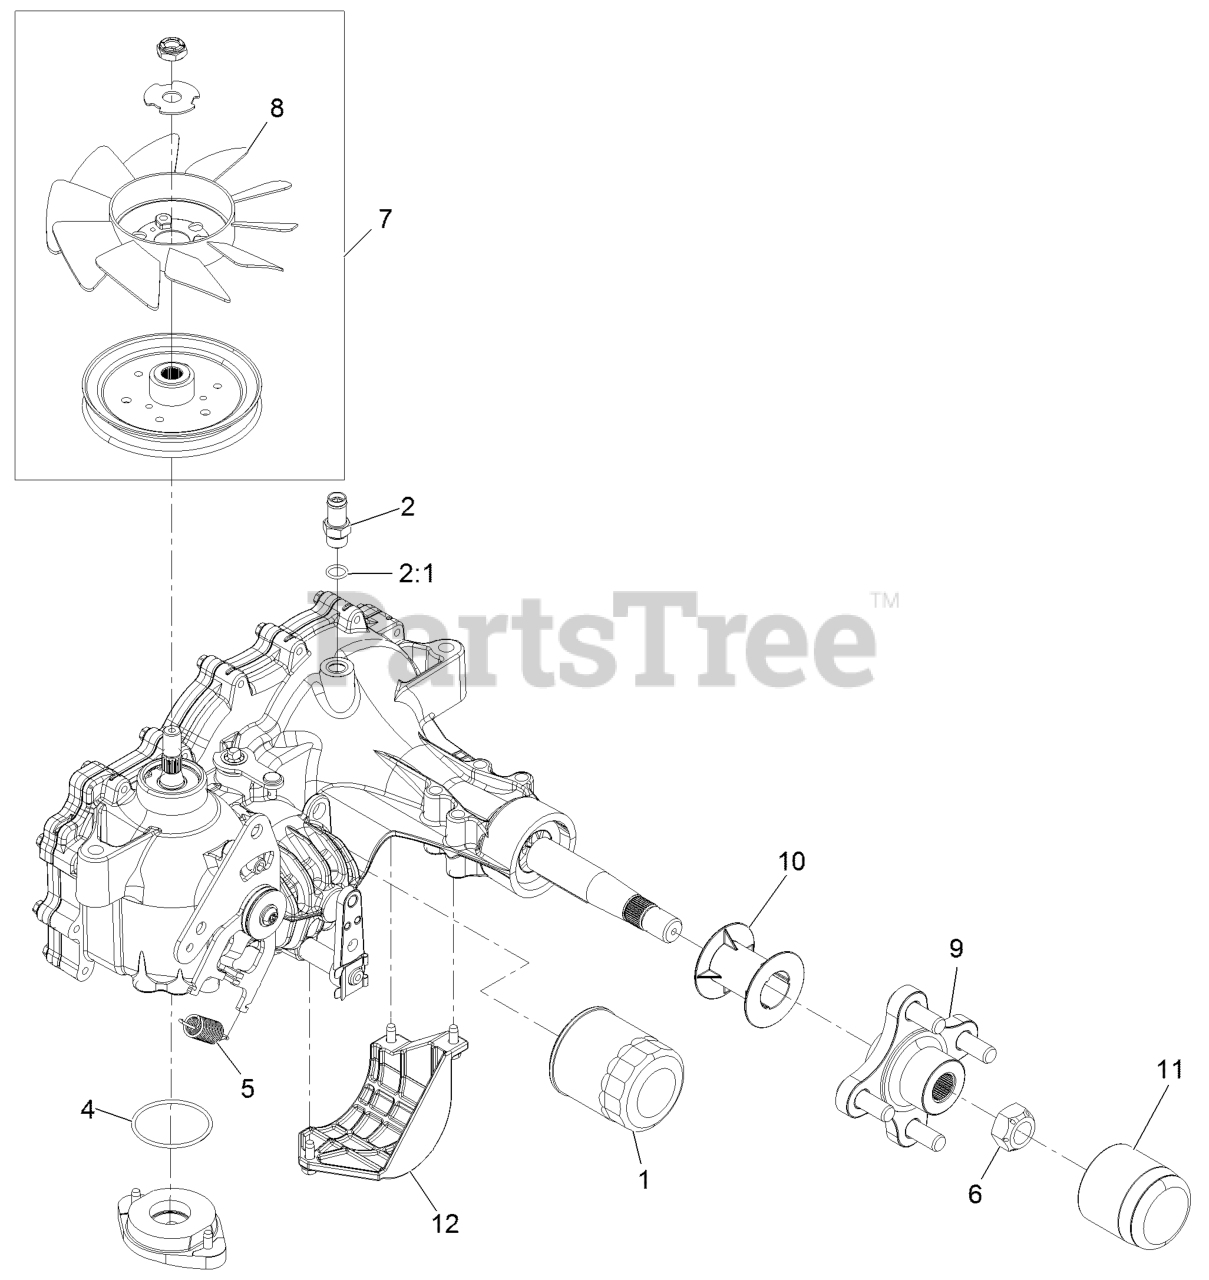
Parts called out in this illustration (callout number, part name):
1	ELEMENT-OIL FILTER, HYD
2	ADAPTER-STRAIGHT
2:1	O-RING
4	O RING-SEAL
5	SPRING-EXTENSION
6	NUT-HUB
9	HUB-OFFSET
10	TUBE-AXLE
11	CAP-AXLE, LONG
12	GUARD-FILTER, LH
